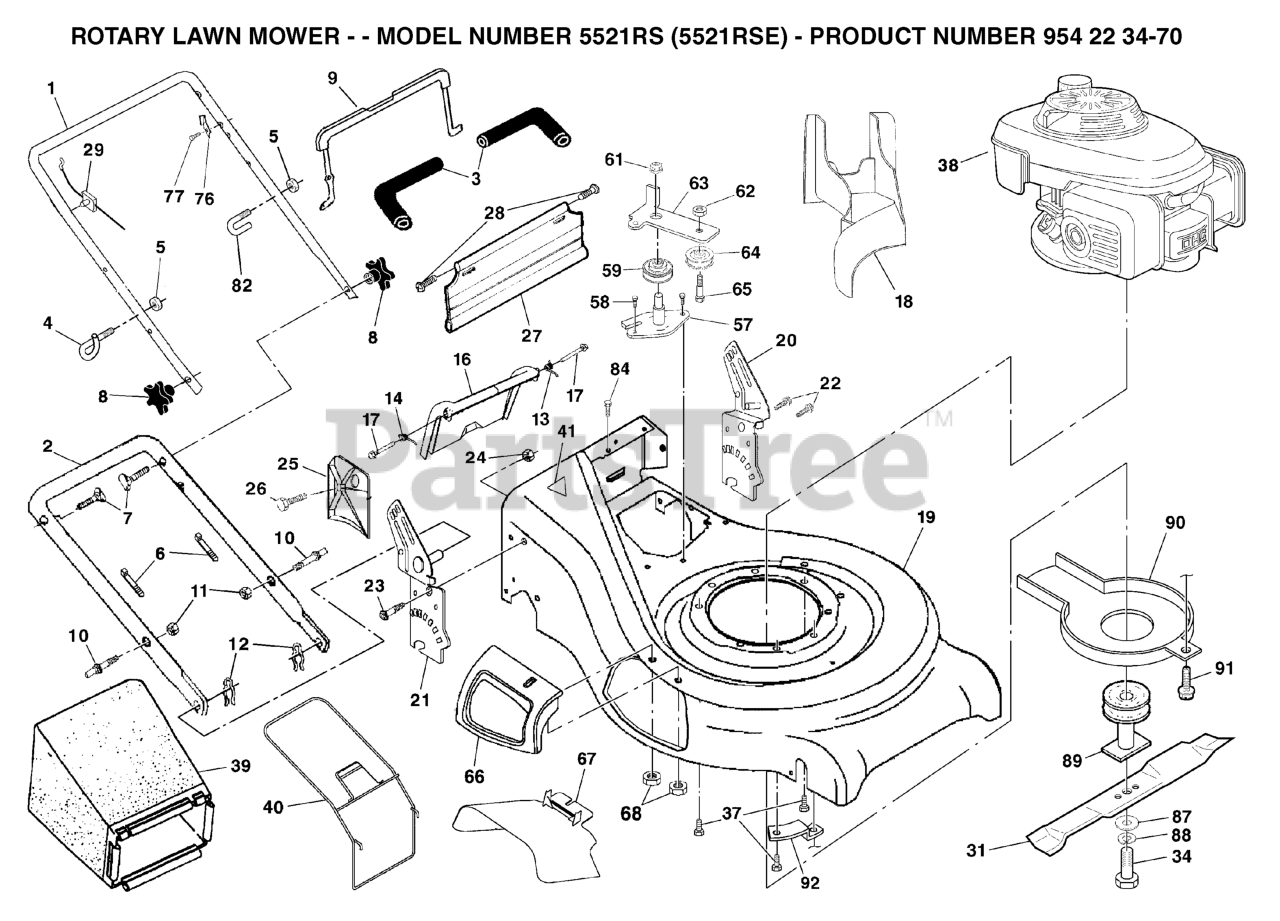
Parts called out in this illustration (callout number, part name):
2	HANDLE, LOWER
3	GRIP.HANDLE.FOAM.WIDE.(1 SIDE)
4	ROPE, GUIDE
5	NUT
6	TIE GUIDE
7	BOLT, HANDLE 5/16-18X1.75
8	KNOB.HANDLE.STAR.HUSQ.GRAY
9	BAIL, FLAT AUTO WALK
11	NUT.CENTERLOCK.5/16-
12	HAIRPIN COTTER
13	SPRING.RH.REAR.DOOR.21.RWGD
14	SPRING.LH.REAR.DOOR.21.RWGD
16	DOOR.REAR.PLASTIC.21.RWGD.BLAC
18	PLUG, MULCHER
22	SELF-TAPPING SCREW 5/16-18X3/4
23	BOLT, HEX HEAD 5/16-18
24	NUT.71038.31-18.HEX.NYLOCK
25	CLIPPING DEFLECTOR
28	HINGE SCREW
29	ENGINE ZONE CONTROL CABLE
31	BLADE.21.PUSH/RWGD/FWG
34	SCREW, HEX HD 3/8-24 X 1-3/8
37	BOLT 3/8-16X1-1/8
40	GRASS CATCHER FRAME
41	DECAL HYT
57	BRACKET ASSEMBLY
59	PULLEY ASSY
61	NUT
62	LOCKNUT
63	IDLER ARM
64	IDLER PULLEY
65	SHOULDER BOLT
66	MULCHER DOOR ASM.
67	DEFLECTOR, DISCHARGE
76	BRACKET UPSTOP
87	WASHER,HARDEN
88	LOCKWASHER
89	BLADE ADAPTOR / PULLEY
90	DEBRIS SHEILD
91	SCREW
92	BRACKET
